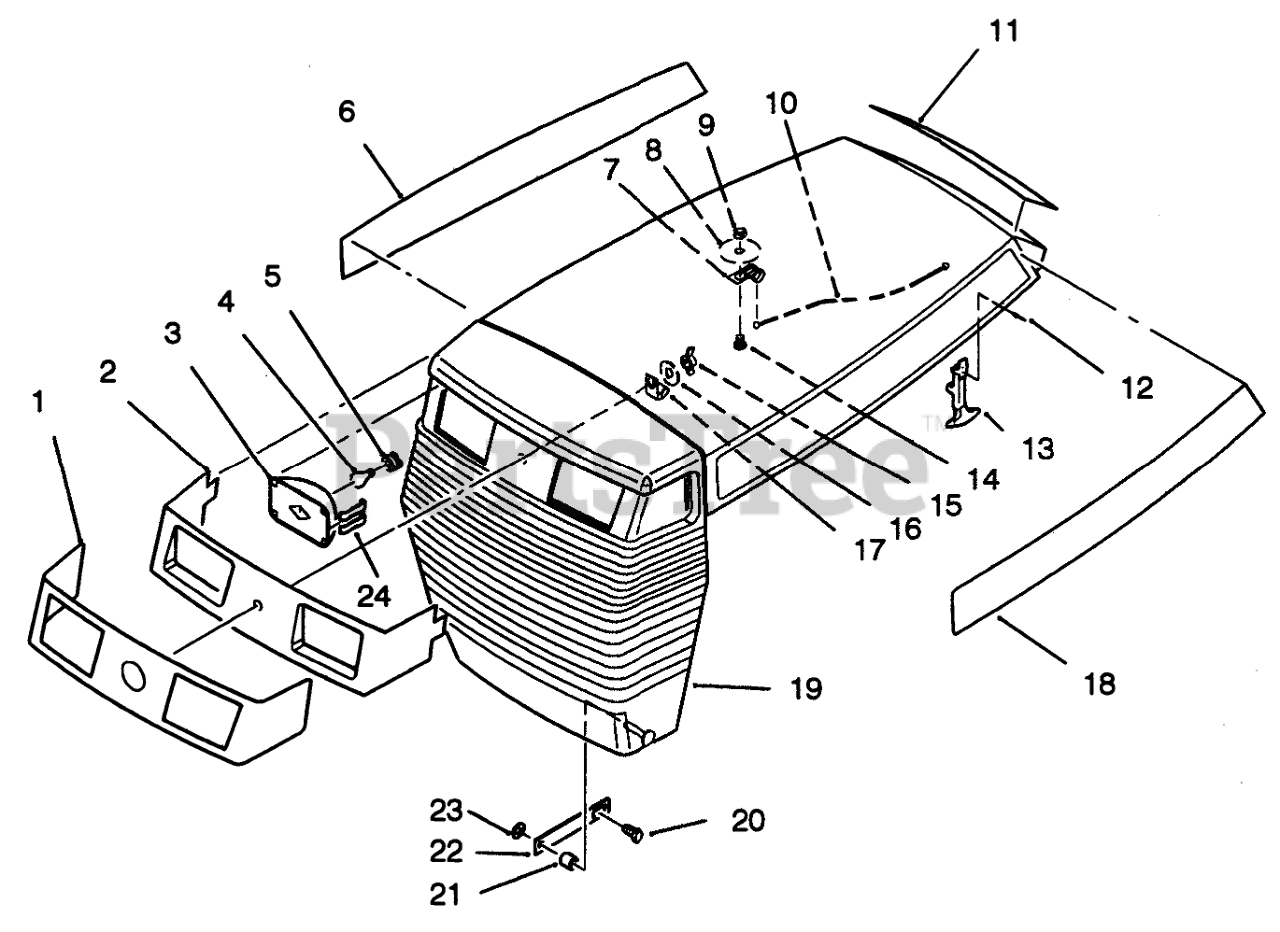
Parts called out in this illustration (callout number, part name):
1	DECAL-FRONT HOOD
2	LIGHT-BAR BLACK
3	LIGHT POD
4	BULB
5	SOCKET-HEADLIGHT
6	DECAL-HOOD 244-H R H
7	CLEVIS
8	WASHER-BACKING
9	Nut
10	CABLE-ASS'Y
11	Decal-Hood Rear
12	RIVET-POP
13	HANDLE ASM
14	SCREW
15	WING NUT
16	WASHER
17	J-CLIP
18	DECAL-HOOD 244-H L H
19	Hood
20	Screw
21	SPACER
22	STRAP R
23	PUSH-NUT 5/16
24	RETAINER
